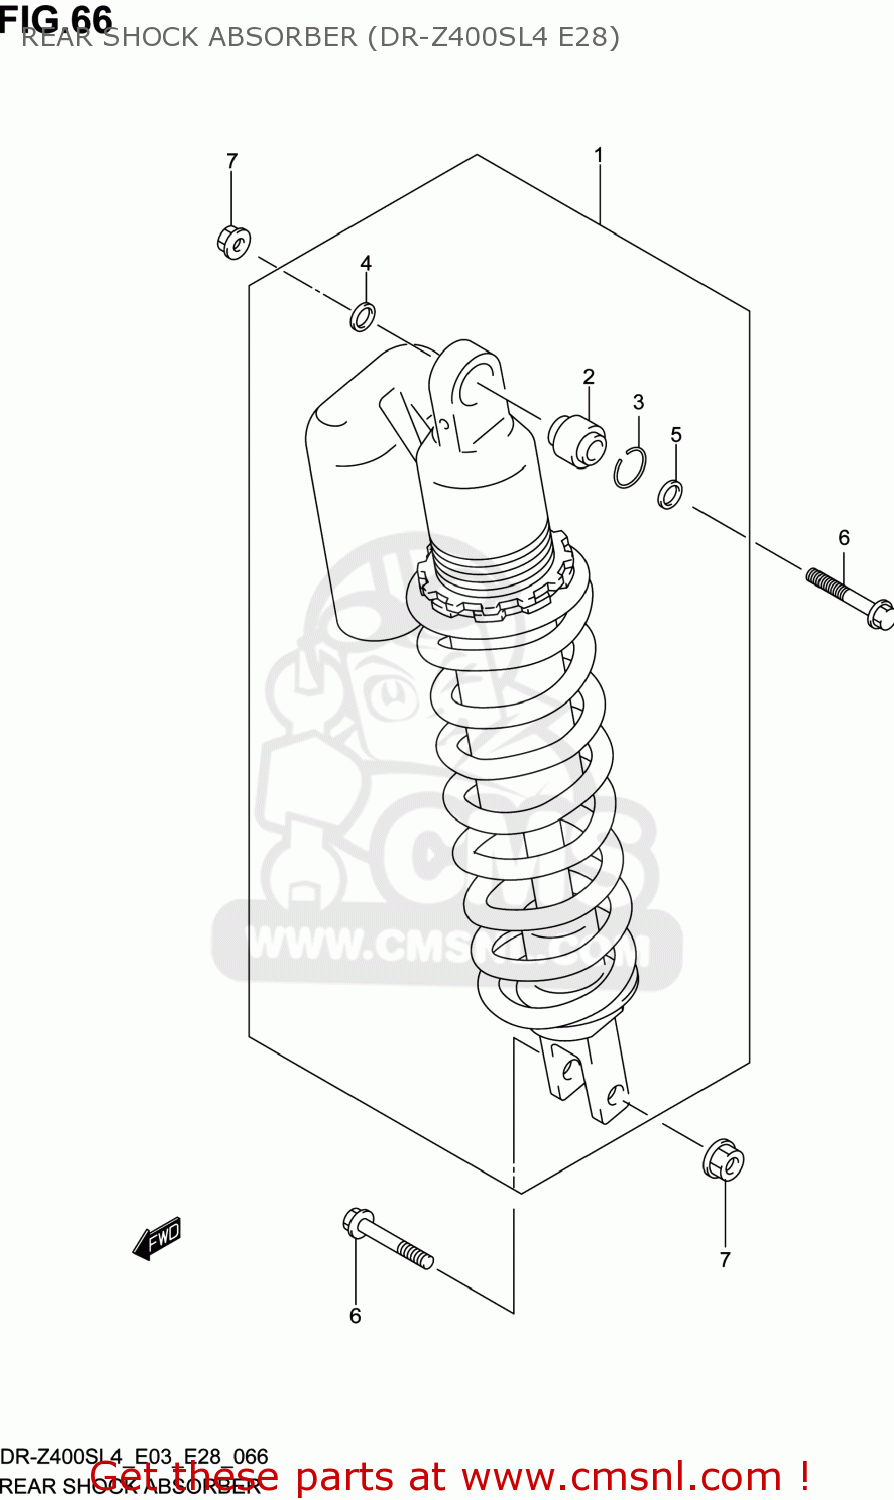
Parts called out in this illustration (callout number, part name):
1	ABSORBER ASSY,RR SHOCK
2	BEARING,RR SHOCK ABSORBER
3	RING,STOPPER
4	SEAL,DUST UPR,R
5	SEAL,DUST UPR,L
6	BOLT(10X47.5)
7	NUT
